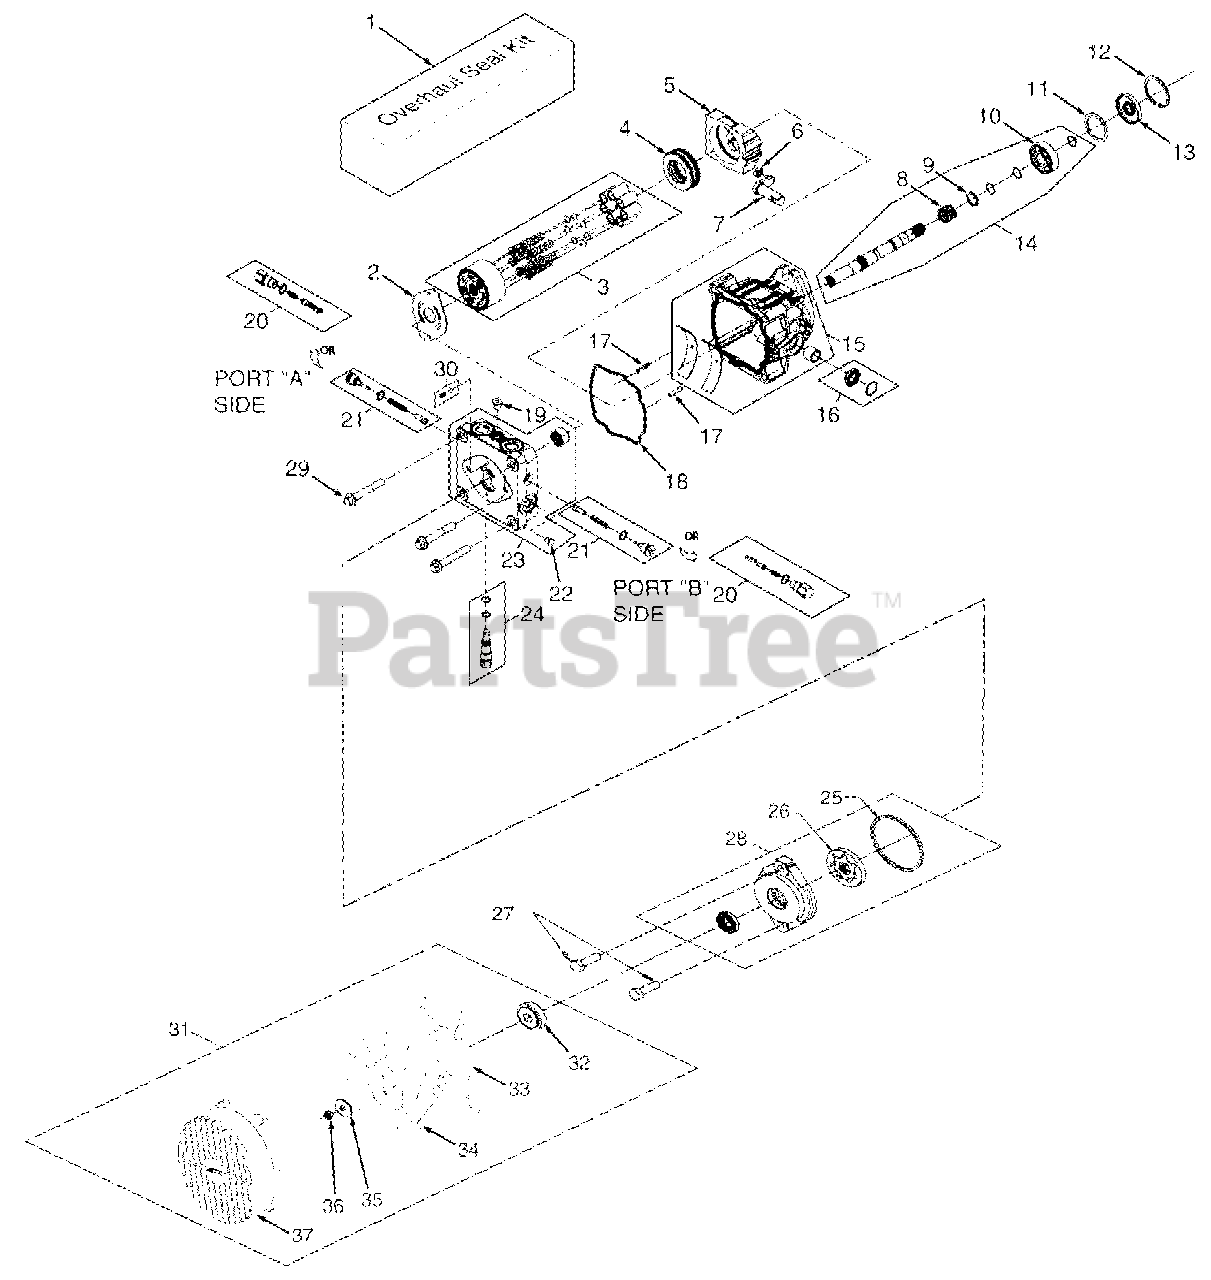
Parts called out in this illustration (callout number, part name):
1	Overhaul Seal Kit
2	Valve Plate
3	Cylinder Block Kit - 16cc
4	Thrust Ball Bearing Assembly
5	Variable Swashplate
6	Slot Guide
7	Trunnion Arm
8	Block Spring
9	Block Thrust Washer
10	Shaft Ball Bearing
12	Retaining Ring
14	Kit, Pump Shaft (keyed thru taper)
15	Housing Kit
16	Trunnion Seal Kit
18	O-Ring
19	Straight Thread Plug
20	Shock Valve Kit (.031 Orifice)
21	Shock Valve Kit (.024 Orifice)
22	Straight Thread Plug
23	End Cap Kit
24	Bypass Valve Kit
26	Gerotor Assembly (.19 cu.in./rev.)
27	Socket Head Cap Screw (M8 x 1.25-25mm)
28	Charge Pump Kit (.19 STD. Splined)
29	Hex Screw, Flanged Head (M10 x 1.50-65mm)
30	Charge Relief Kit
31	Fan Kit
33	Bracket, Shroud
35	Washer
37	Shroud
